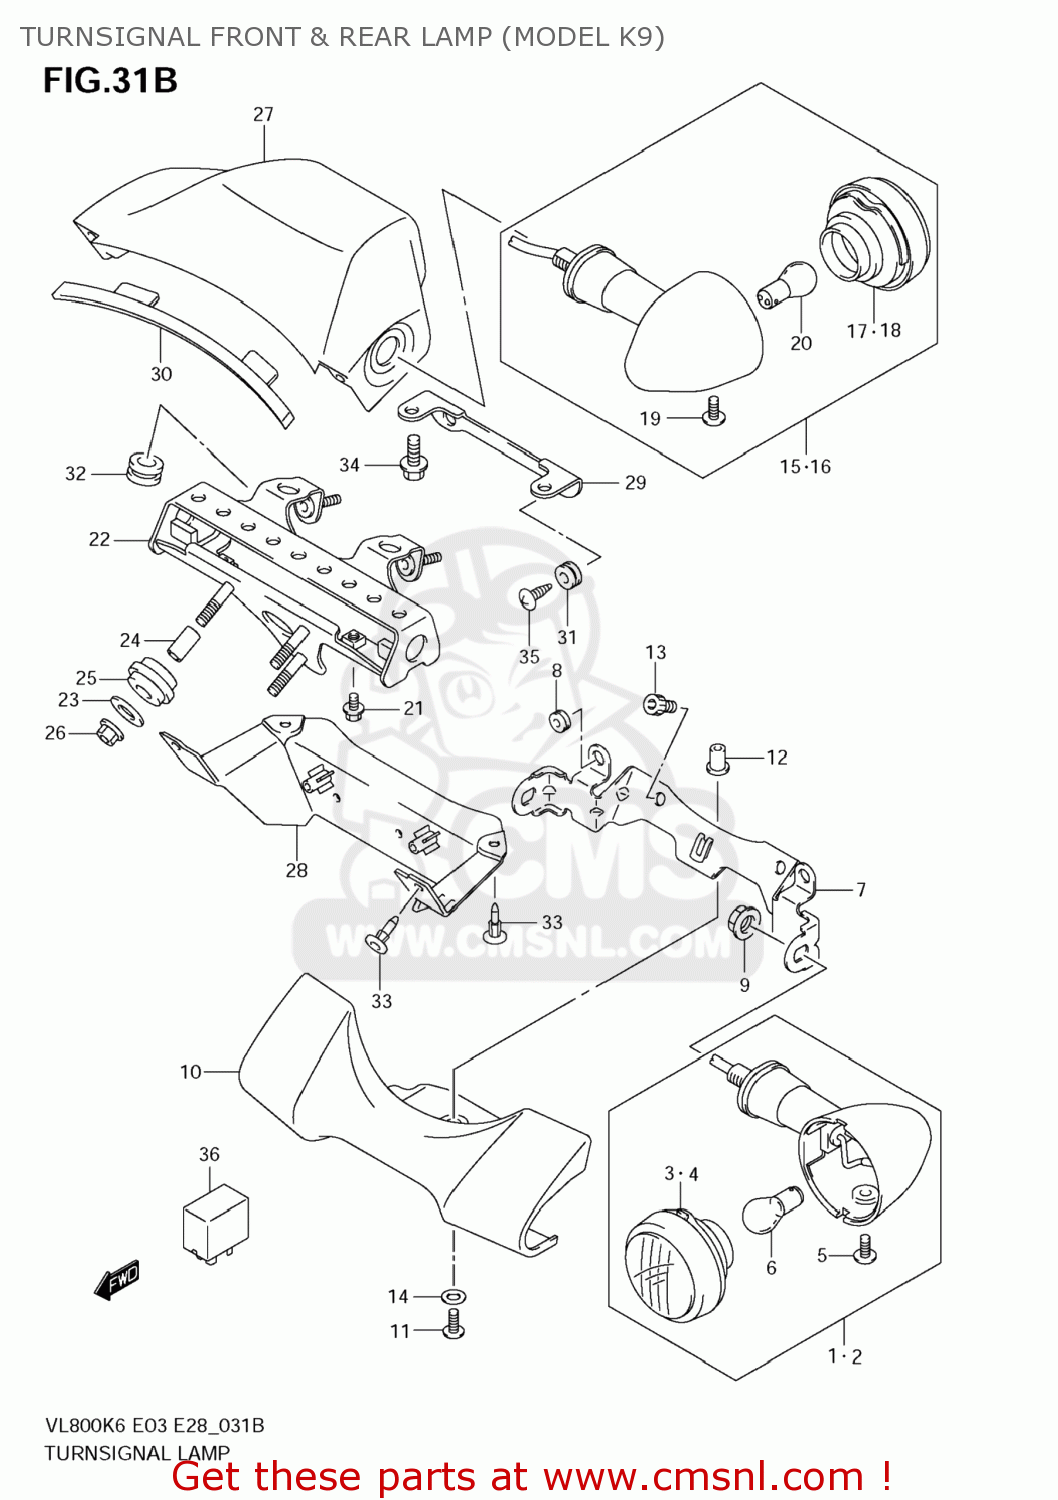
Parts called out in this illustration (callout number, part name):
1	LAMP ASSY,FR TURN SIGNAL,R
2	LAMP ASSY,FR TURN SIGNAL,L
3	LENS
4	LENS
5	SCREW(4X10)
6	BULB(12V21/5W)
7	BRACKET
8	CUSHION
9	NUT
10	COVER,FR TURNSIGNAL
11	SCREW(5X16)
12	NUT
13	BOLT
14	WASHER(5.5X14X1.2)
15	LAMP ASSY,REAR
16	LAMP ASSY,REAR
17	LENS
18	LENS
19	SCREW(4X10)
20	BULB(12V21W)
21	BOLT(6X14)
22	BRACKET,REAR T
23	WASHER(6.5X20X1.2)
24	SPACER(6.4X10X18)
25	CUSHION
26	NUT
27	COVER,RR TURNSIGNAL UPR
28	COVER,RR TURNSIGNAL LWR
29	BRACKET,RR TURNSIGNAL COVER
30	GASKET,RR TURNSIGNAL COVER (NAS)
31	CUSHION
32	CUSHION
33	CLIP(BLACK)
34	BOLT
35	SCREW
36	RELAY ASSY,TURNSIGNAL LAMP
